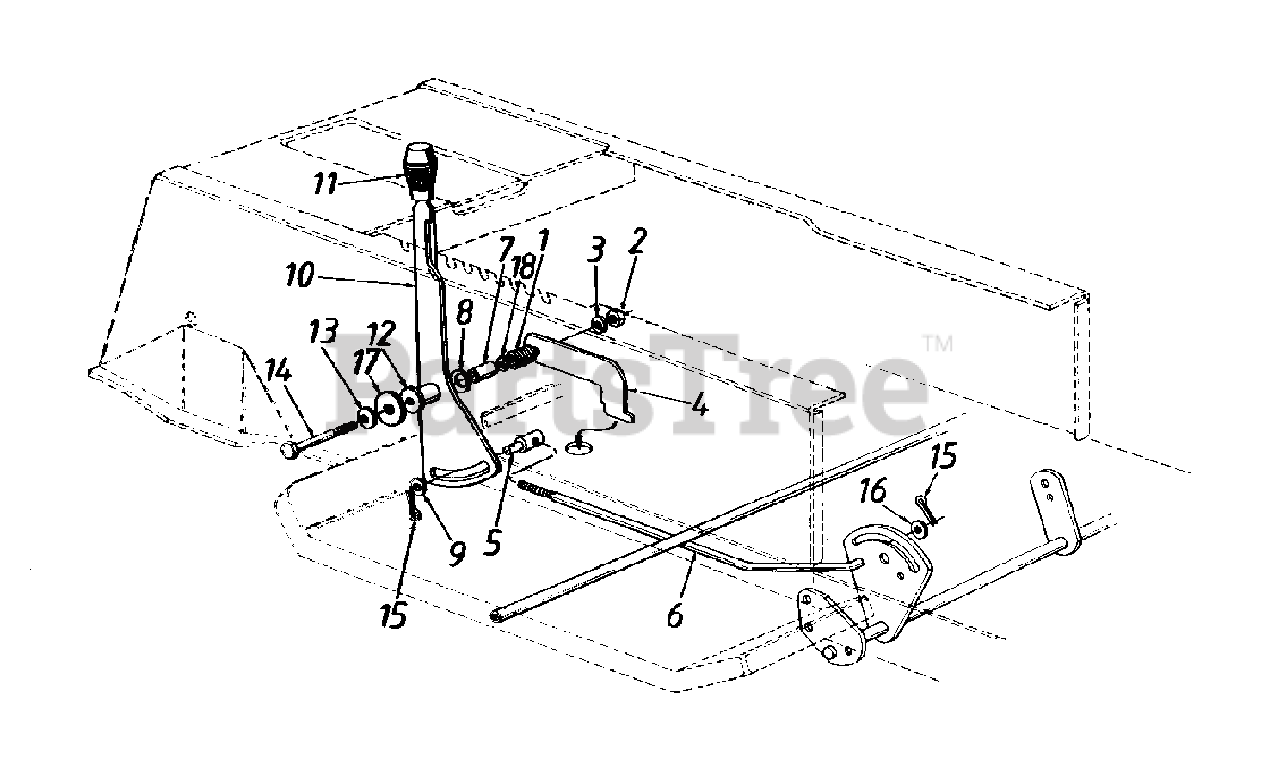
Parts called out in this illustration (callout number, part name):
1	Compression Spring
2	Hex Nut 5/16-18 Thd.
3	L-Wash. 5/16" I.D.
4	Shift Lever Support
5	Ferrule 3/8-24 Thd.
6	Speed Control Rod
7	Spacer 1.56" Lg.
8	Bell-Wash. .505" I.D. x 1"
9	Fl-Wash. .385" I.D. x .87"
10	Speed Selector Lever
11	Shift Knob
12	Spacer 1.46" Lg.
13	Fl-Wash. .345" I.D. x .88"
14	Hex Bolt 5/16-18 x 3.25" Lg.
15	Cotter Pin 3/32" Dia. x 1"
16	Fl-Wash. .469" I.D. x .88"
17	Fl-Wash. .34" I.D. x 2.25"
18	Speed Nut 5/16-18 Thd.
